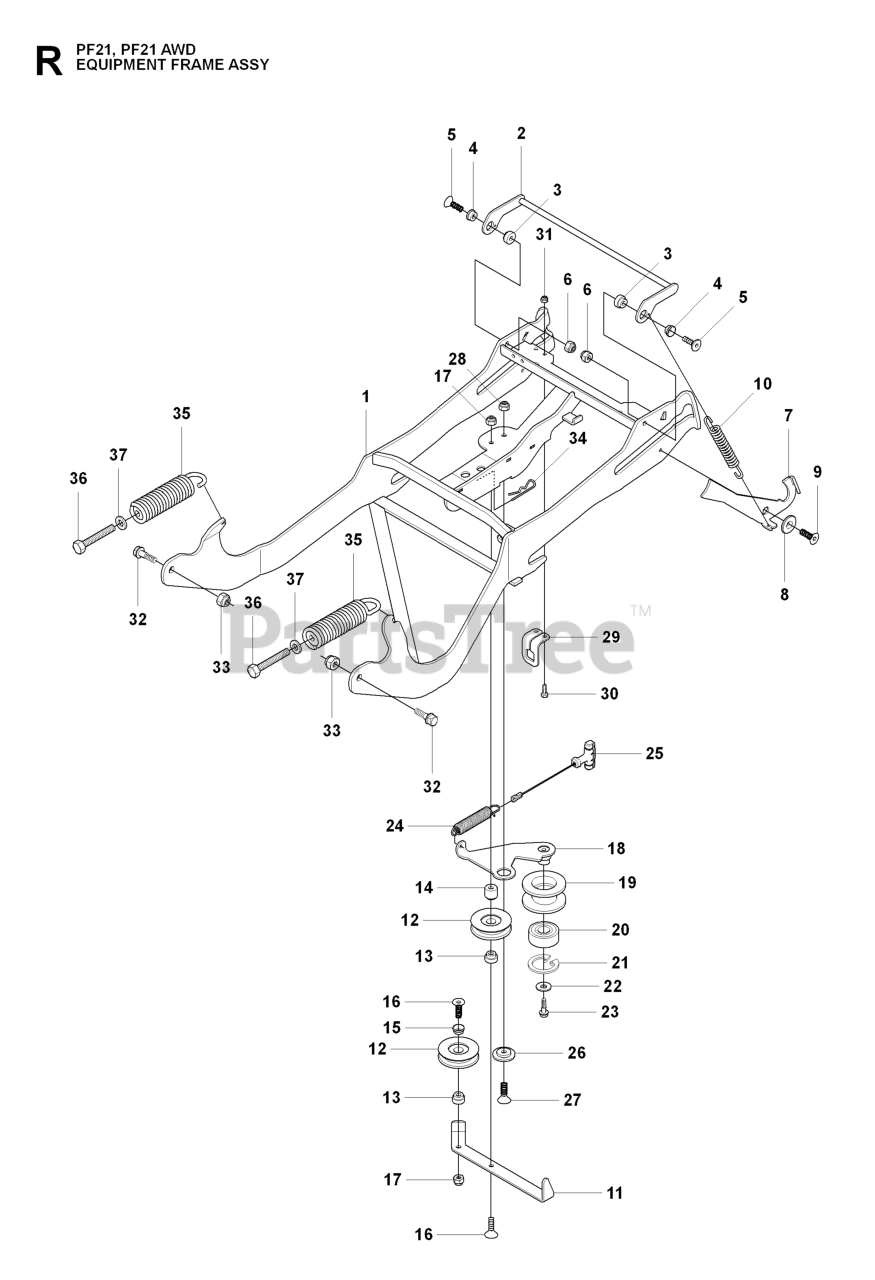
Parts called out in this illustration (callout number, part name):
6	LOCKNUT M8
8	SPACER
9	BOLT REAR WHEEL
12	PULLEY ASSY
17	LOCKNUT M8
19	%PULLEY
20	BALL BEARING 6004-2RS1
21	RETAINING RING
26	WASHER
28	LOCKNUT M8
30	BOLT FLANGE - M6X20
31	LOCKNUT M6
37	WASHER
